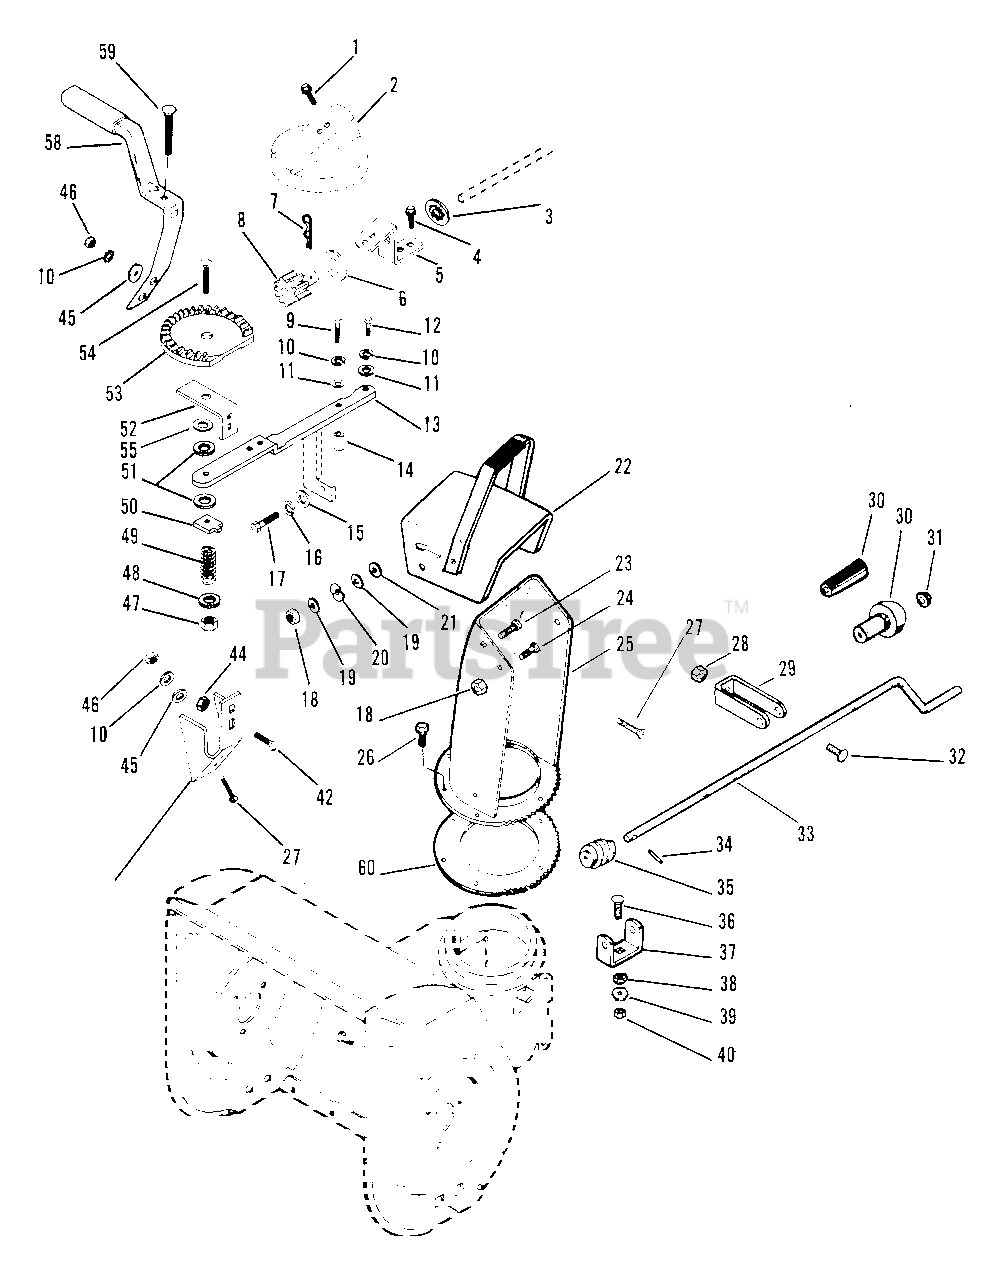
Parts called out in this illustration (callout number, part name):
1	SCR-TAP .250-20X.37 HWH PL TR
2	GEAR COVER
3	PUSHNUT .625
4	SCR-TAP .250-20X.50 HXSLHDPL
5	BRACKET-GEAR
6	WSHR-FL-STL .630X1.005X.062 PL
7	PIN-HAIR INT .08X.38X1.42 YWZC
8	PINION-CHUTE
9	BLT-HEX .25-20X1.50 PL GR5
10	WSHR-LK .250X.077 HVY PL
10	WSHR-LK .312X.097 PL HVY
11	WSHR-FL-STL .328X.875X.062 PL
12	BLT-HEX .31-18X.63 PL GR 2
13	STRAP
13	STRAP-CHUTE CONTROL
14	SPACER .280X.625X.760
15	WSHR-FL-STL .328X.875X.062 PL
16	WSHR-LK .312X.097 PL HVY
17	BLT-HEX .31-24X.75 PL GR5
18	NUT-LK .312-18 GR A PL
19	WSHR-FL-STL .323X.625X.062 PL
20	WAVE WASHER .390X.655X.110
21	WSHR-PLASTIC .390X.875X.062
22	DEFLECTOR W/DECAL
23	BLT-RDHDSQNK .31-18X.75 SHT PL
24	BLT-HEX .31-18X.50 PL GR2
25	DISCHARGE CHUTE
25	CHUTE-DISCHARGE
26	SCR-TAP 8-32X.38 SL HWH PL 23
27	SCR-SKH .25-20X.75 FLTCNTRSK
28	NUT-LK-CTR .250-20 PL
29	BRACKET WITH DECAL
30	GRIP
30	KNOB
31	CAP, 3/8 ROD YWZC
32	BLT-RDHDSQNK .25-20X1.25 GR5PL
33	CHUTE CONTROL CRANK
33	CHUTE CRANK
34	PIN-ROLL .125X.75
35	WORM GEAR
36	BLT-RDHDSQNK .31-18X.75 GR5 PL
37	PUSH NUT, .25
38	WSHR-LK .313X.062
39	WSHR-LK-EXT .375X.035 PL
40	NUT-HEX .312-18
42	BLT-RDHDSQNK .25-20X.62 PL
43	STRAP, CHUTE
44	NUT-LK-FLG .250-20 PL
45	WSHR-FL-STL .312X.875X.18 PL
46	NUT-HEX .250-20 PL
47	NUT-LK-CTR .375-16 GR A PL
48	WSHR-FL-STL.406X.812X.065PL
49	SG-COMP .187X.56X1.62
50	FRICTION PLATE
51	FRICTION WASHER
52	GEAR STRAP
53	CHUTE GEAR
54	BLT-RDHDSQNK .38-16X2.25 SHTPL
55	WSHR-FL-STL .380X1.50X.062 PL
58	CHUTE HANDLE W/PLASTISOL
59	BLT-RDHDSQNK .38-16X2.00 SHTYW
60	GEAR - LOWER COLLAR
